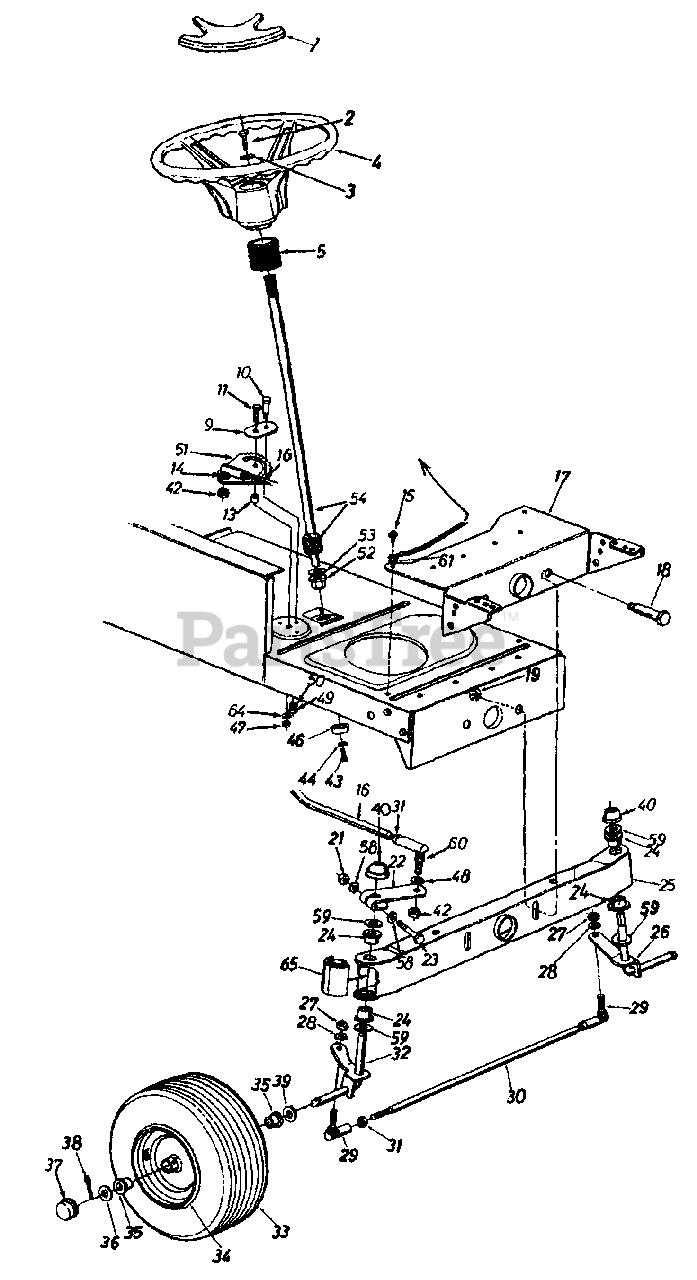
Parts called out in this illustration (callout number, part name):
1	Steering Wheel Cap
2	Hex Bolt 5/16-18 x 1" Lg.
3	Belleville Wash. .345" I.D.
4	Steering Wheel
5	Steering Bellow - 9"
9	Retainer Plate
10	Shoulder Bolt .437" Dia. x .35 Lg. 5/16-18 Thd.
11	Hex Bolt 3/8-24 x 1.0" Lg. (Gr. 5)
13	Spacer .380" I.D. x .625" O.D. x .227
14	L-Wash. 3/8" I.D. (H.D.)
15	Hex Wash. Hd. Self-Tap Scr.
16	Steering Drag Link
18	Shoulder Bolt .498" Dia. x 2.04 Lg. 3/8-16 Thd.
19	Flanged L-Nut 3/8-16 Thd.
21	Hex L-Nut 5/16-24 Thd.
22	Steering Arm Front Axle
23	Hex Bolt 5/16-24 x 2.00" Lg. (Gr.5)
24	Hex Flg. Brg. .632 I.D.
26	Front Axle Ass'y.- L.H.
27	Hex Nut 3/8-24 Thd.
28	L-Wash. 3/8" I.D.
29	Ball Joint 3/8-24 Thd.
30	Tie Rod (Adjustable)
31	Hex Jam Nut 3/8-24 Thd.
32	Front Axle Ass'y.- R.H.
36	Fl-Wash. .635 I.D. x 1.59" O.D.
37	Front Wheel Hub Cap
38	Cotter Pin 1/8" Dia. x 1.25"
39	Fl-Wash. .640" I.D. x 1.24" O.D.
40	Push Cap 5/8" Dia. Rod
42	Hex Jam Nut 3/8-24 Thd.
43	Hex Patch Bolt 5/16-18 x .62"
44	L-Wash. 5/16" I.D.
46	Cap
47	Hex Cent. L-Nut 3/8-24 Thd.
48	L-Wash. 3/8" I.D.
49	Hex Cent. L-Nut 5/16-18 Thd.
50	L-Wash. 5/16" I.D.
51	Steering Gear Segment
52	Hex Flg. Brg. .634 I.D.
53	Fl-Wash. (Hardened)
54	Steering Shaft
58	Wave-Wash. .32" I.D. x .62" O.D
59	Fl-Wash. (Hardened)
60	Drag Link Ball Joint 3/8-24 Thd.
61	Ext. L-Wash. 5/16" I.D.
64	Bell-Wash. .39" I.D. x 1.38" O.D.
65	Pivot Bar End Cap
